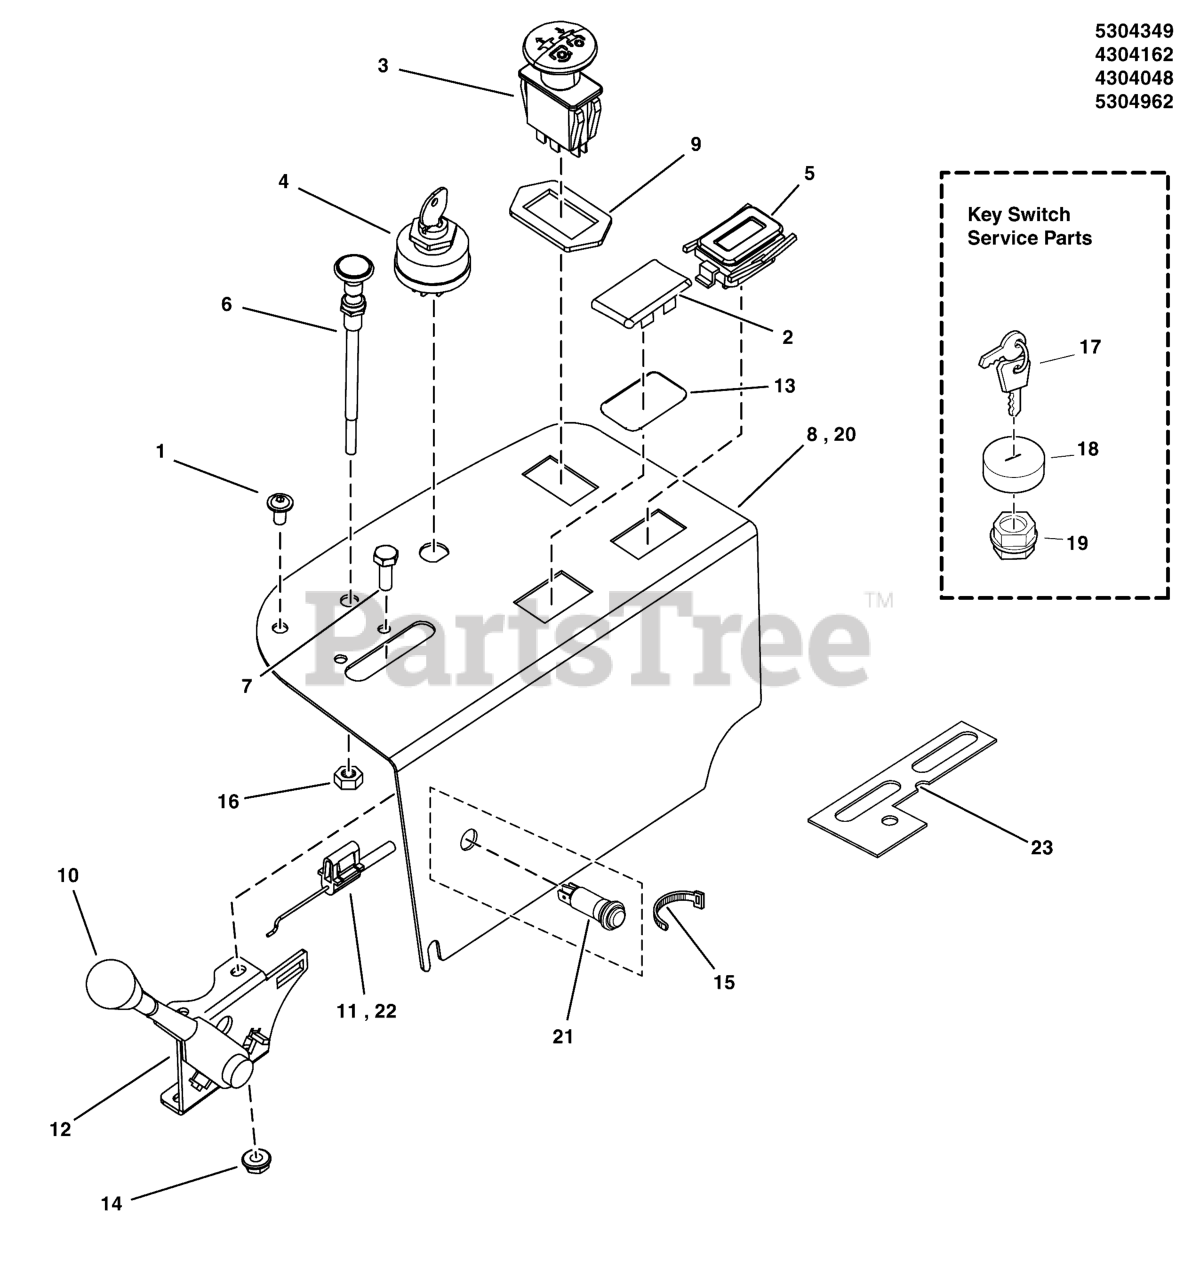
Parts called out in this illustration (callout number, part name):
1	SCREW, ALLEN HEAD 1/4-20X.500 ZINC PHOS
2	PLUG, .820X1.44 HOLE, BLACK PLASTIC
3	SWITCH-PTO PUSH
4	SWITCH, IGNITION, 6 POST
5	HOURMETER
6	CABLE, CHOKE CONTROL, 51" (Z)
7	SCREW, #10-24 X 3/4" ROUND PHILLIPS
8	PANEL, Control - Black
9	RING, SWITCH RETAINER
10	THROTTLE CONTROL HANDLE/KNOB
11	CABLE, THROTTLE 47"
12	LEVER, THROTTLE CONTROL, HEAVY-DUTY
13	O-RING, 7/8" ID X 1/16" W
14	NUT, Hex, Nylon Lock, #10-24
15	TIE, SELF-LOCKING, 12"
16	NUT, 3/8-24 HEX (SV)
17	KEY, IGNITION MOLDED SET
18	COVER, PLASTIC, SNAP ON
19	PLASTIC NUT
20	PANEL, CONTROL, IS2100/3200 - BLK
21	LIGHT, INDICATOR, PANEL, LED, RED
22	CABLE, THROTTLE, 52"
